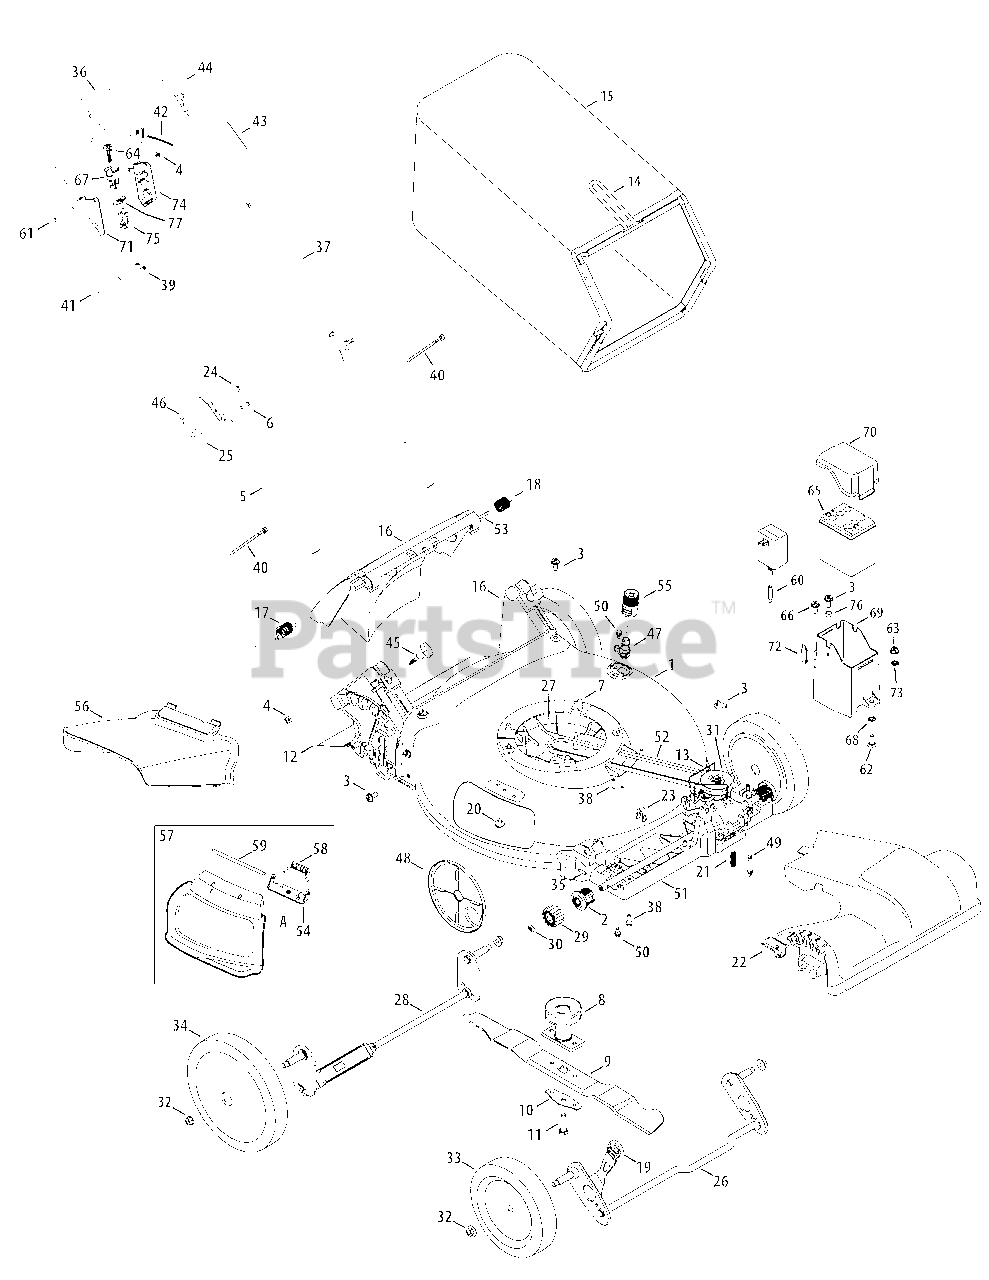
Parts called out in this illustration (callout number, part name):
1	Deck , 21"
2	Bearing Assembly
3	Screw, 5/16-14 x .750
4	Nut, Sq., 1/4-20
5	Lower Handle
6	Carriage Screw ,5/16-18
7	Screw, 3/8-16 x 1.00
8	Blade Adapter (159cc)
9	Mulching Blade
10	Blade Bell Support
11	Screw, 3/8-24 x 1.50
12	Trailing Shield
13	Transmission Wire
14	Grass Catcher Frame
15	Grass Bag, Yardman
16	Rear Discharge Door Assembly
17	Torsion Spring - RH
18	Torsion Spring - LH
19	Adjustment Lever Knob
20	Screw, 1/4-20 x .500
21	Compression Spring
22	Front Cover
23	Front Axle Clip
24	Nut, Flange Lock, 1/4-20
25	Wing Knob
26	Front Axle Assembly
27	Engine Baffle
28	Rear Axle Assembly
29	Spur Gear, 14T - RH
29	Spur Gear, 14T - LH
30	Screw, 1/4-20 x .390
31	Transmission Assembly
32	Flange Lock Nut, 3/8-16
33	Front Wheel, Gray, Pin Bar
34	Rear Wheel, 11", Oyster Gray
35	Dowel Pin
36	Control Lever Assembly
38	Screw, 1/4-15 x .750
40	Cable Tie
41	Rope Guide
42	Drive Cable
43	Control Cable (5X65RU)
44	Blade Control
45	Wing Nut
46	Sldr. Screw, .375 x .126 x 1/4-20
47	Water Nozzle
48	Wheel Dust Cover
49	Spring Body
50	Scr., Shldr., 1/4-20 x .50
51	Lower Tray
52	V-Belt
53	Pivot Rod
54	Chute Deflector Bracket
55	Water Nozzle Adapter
56	Side Discharge Chute
57	Mulch Plug
58	Torsion Spring
59	Hinge Pin
60	Battery Charger
61	Screw, 1/4-20 x 1.75
62	Bolt, Carr., 5/16-18 x 1.00
63	Nut, Hexlk, 5/16-18
64	Key
65	Battery
66	Scr., Sldr., 5/16-14 x .972
67	Key Switch
68	Speed Nut
69	Battery Housing
70	Battery Housing Top
71	Electric Start Housing, RH
72	Lid Seal
73	Washer, Bell, .340 x .872 x .080
74	Electric Start Housing, LH
75	Plunger Switch
76	Spacer, .340 x .460 x .246
77	Retainer Bracket
